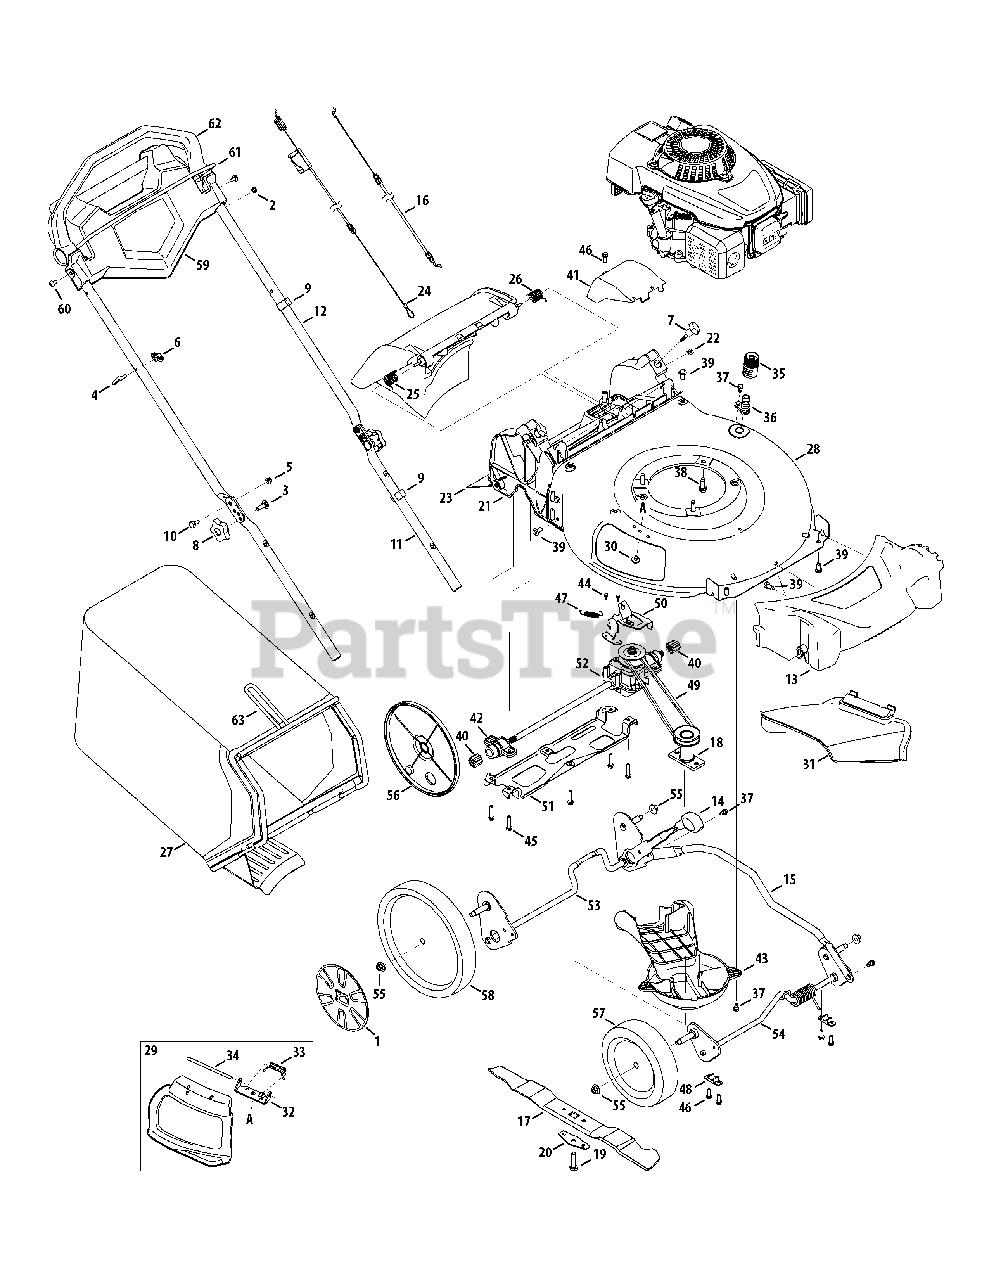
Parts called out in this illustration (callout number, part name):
1	Hubcap - Front
1	Hubcap - Rear
2	Spacer
3	Carriage Screw, 5/16-18
4	Rope Guide
5	Nut, Flange Lock, 1/4-20
7	Wing Knob
8	Star Knob
9	Conduit Clip
10	Shdr. Screw, .375 x .126 x 1/4-20
11	Lower Handle
12	Upper Handle
13	Front Cover
14	Adjustment Knob
15	Tube, Link
16	Control Cable
17	Mulching Blade
18	Blade Adapter
19	Screw, 3/8-24 x 1.50
20	Blade Bell Support
21	Rear Discharge Door Assembly
22	Nut, Sq., 1/4-20
23	Trail Shield
24	Drive Cable
25	Torsion Spring - RH
26	Torsion Spring - LH
27	Grass Bag
29	Mulch Plug (Incl. 32-34)
31	Side Discharge Chute
32	Chute Deflector Bracket
33	Torsion Spring
34	Hinge Pin
35	Water Nozzle Adapter
36	Water Nozzle
37	Scr., Shldr., 1/4-20 x .50
38	Screw, tt, 3/8-16 x 1.00
39	Screw, 5/16-14 x .750
40	Spur Gear, 9T
41	Transmission Cover
42	Bearing Assembly
43	Engine Baffle
44	Screw, Hex Washer, .159 x .43
45	Screw, 1/4-15 x 1.25
46	Screw, 1/4-15 x .750
47	Exten. Spring, 2.675
48	Bush., Block
49	V-Belt
50	Transmission Bracket
51	Rear Support Bracket
52	Transmission
53	Rear Hgt. Adjust./Axle Assembly
54	Front Axle Assembly
55	Flange Lock Nut, 3/8-16
56	Wheel Dust Cover
57	Front Wheel, 8 x2
58	Rear Wheel, 11 x 2
59	Handle Console
60	Screw, 1/4-14 x .625
61	Blade Control
62	Premium Drive Control
63	Grass Catcher Frame
